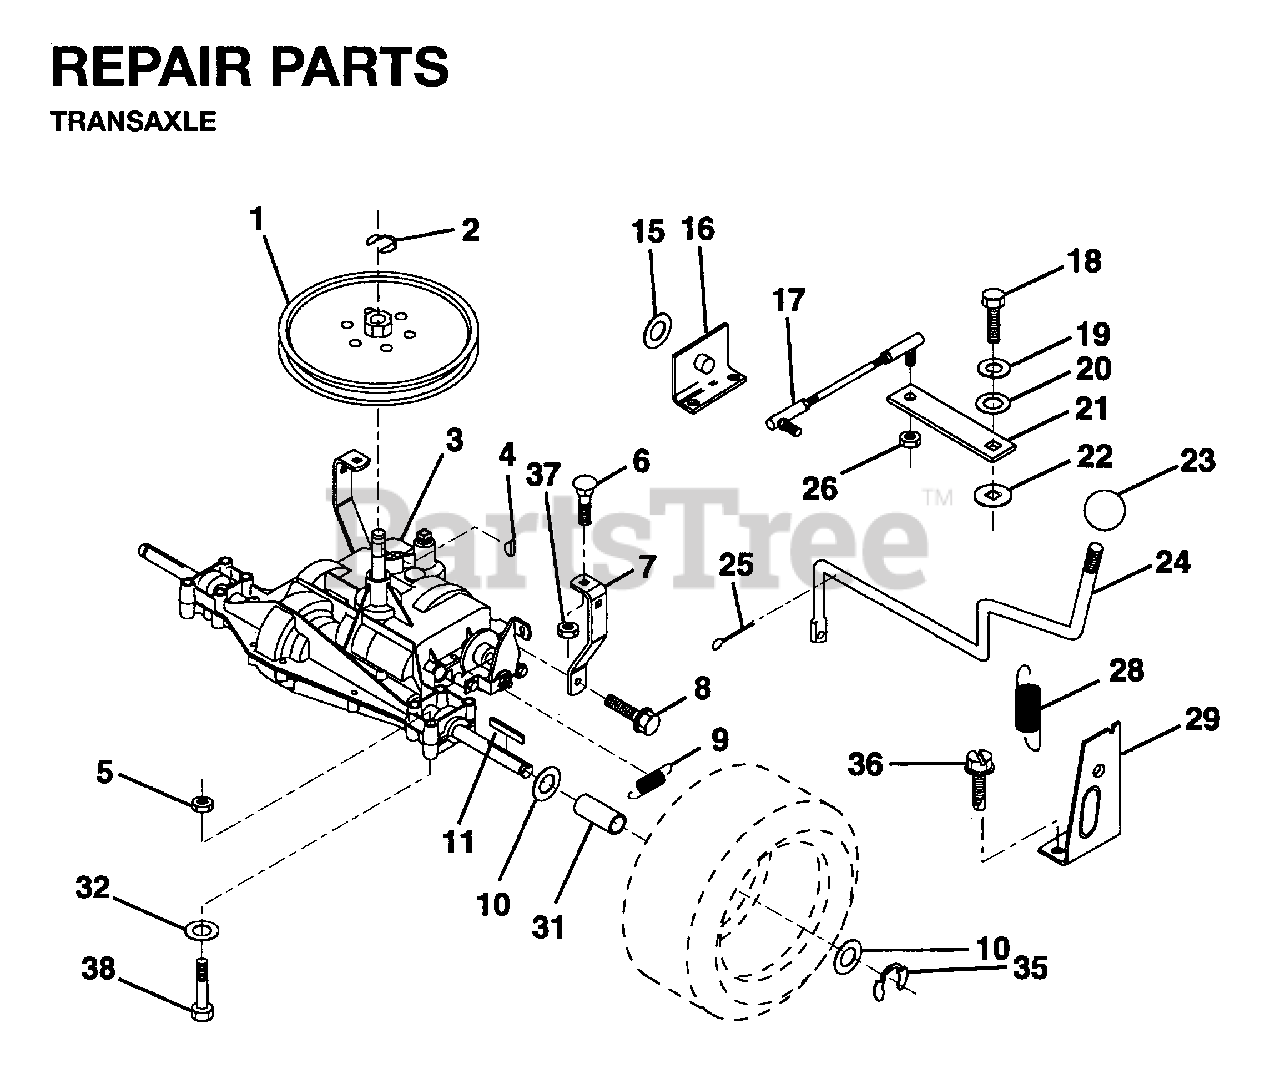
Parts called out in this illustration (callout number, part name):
2	RETAINING RING
5	NUT.71038.31-18.HEX.NYLOCK
6	BOLT
7	STRAP,TORQUE
8	BOLT
9	SPRING T
11	SQUARE KEY
15	WASHER - M12
16	SUPT, HDLE SHT LH
18	BOLT LT
19	LOCKWASHER
20	WASHER - 26X6.5X1.6
22	WASH-SHFT PLT LT
23	KNOB T (1/2-HOLE)
24	ROD, SHIFT
25	PIN COTTER
28	SPRING.EXTENSION
29	SUPPORT HANDLE SHAFT RH
31	SPACER AXLE
32	WASHER - 15X7.3X1.6
35	E-RING LT
36	BOLT
37	LOCKNUT
